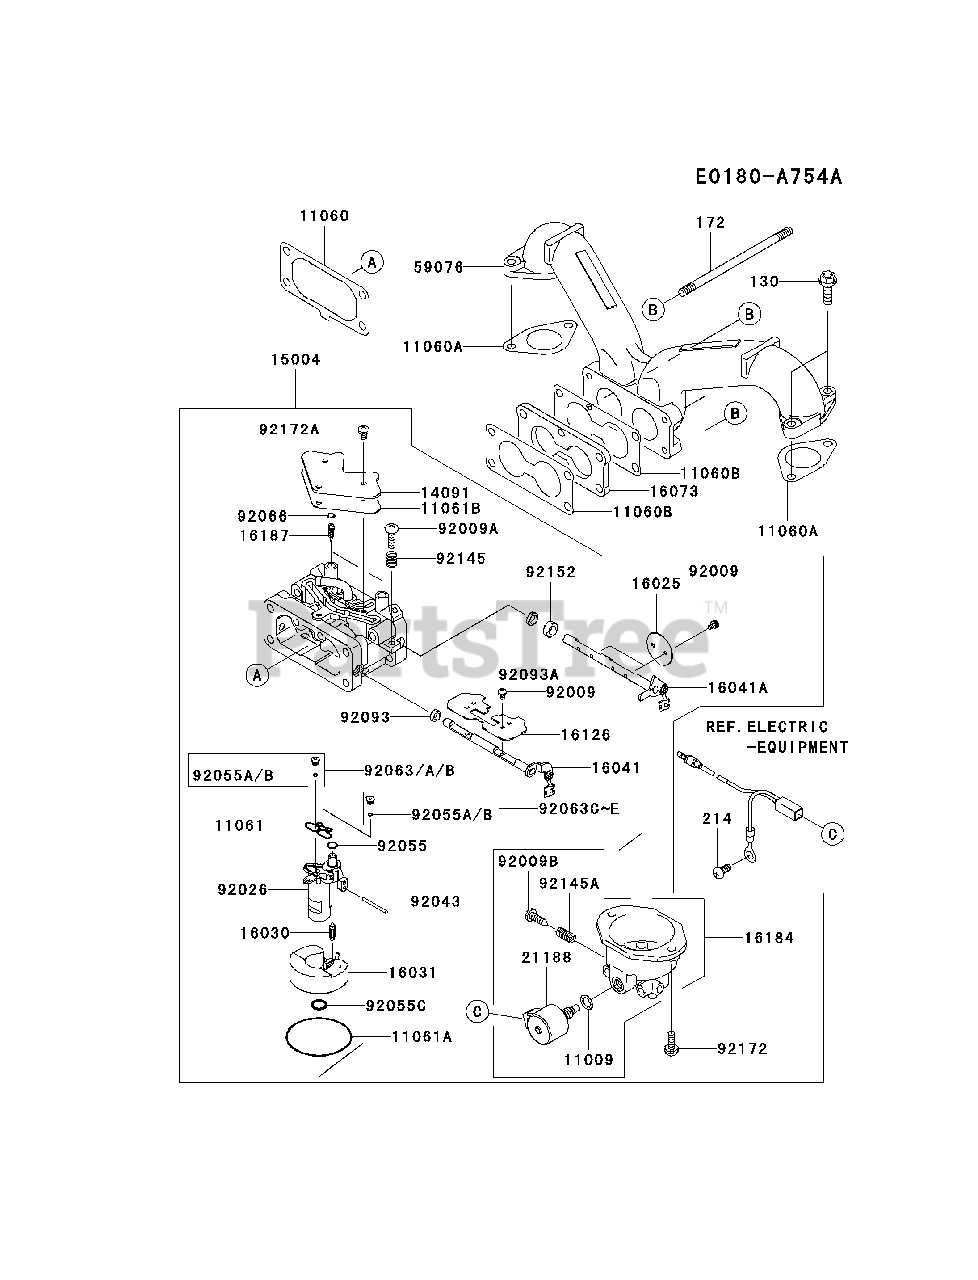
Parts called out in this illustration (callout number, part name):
130	BOLT-FLANGED,6X20
172	BOLT-STUD,6X105
214	SCREW-PAN+-,5X10
